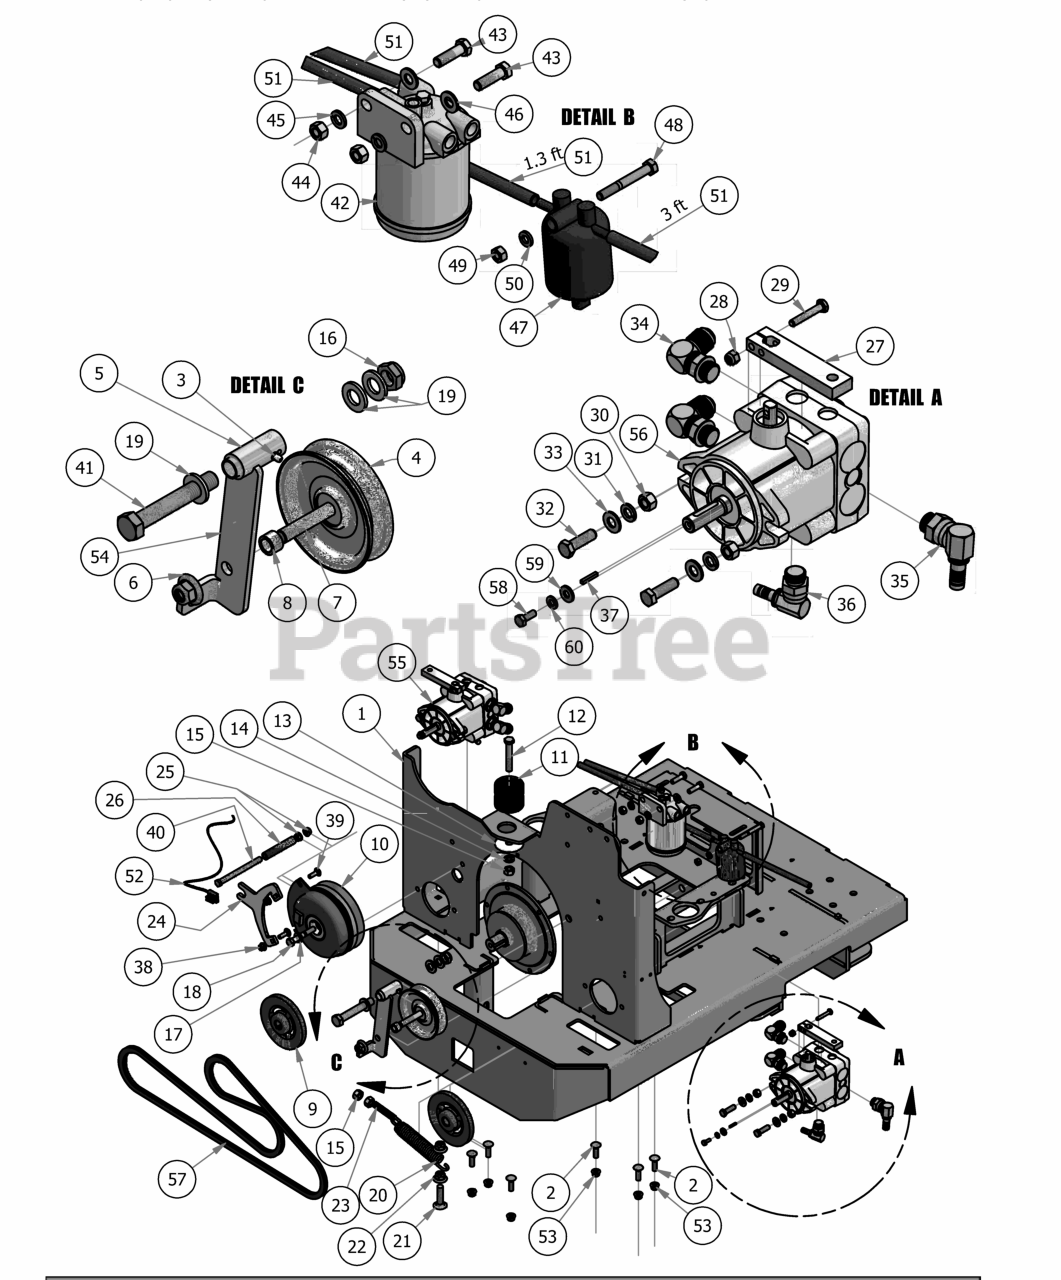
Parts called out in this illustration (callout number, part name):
1	Pump Plate Diesel
2	3/8" x 1 1/4" Carriage Bolt
3	1/4" Drive in Grease Fitting
4	4 3/4" Idler Pulley
5	Pump Idler Bracket only for 61" Deck
6	1/2-13 Nylon Flange Nut-Orange
7	1/2" x 3" Hex Bolt
8	1/2 x 1/2 Spacer
9	5" Pump Pulley
10	Clutch Assembly for Diesel
11	Armor Plated Mount-Rear Mount
12	1/2" x 3" Hex Bolt
13	Snubbing Washer
14	1/2" Lock Washer
15	1/2" Hex Nut
16	5/8" Nylock (1/2 Jam)
17	7/16" Lock Washer
18	7/16" x 2 3/4" Fine Thread Bolt
19	.630 ID x 1.122 OD x .142 THK Plastic Washer
20	Deck Idler Spring
21	1/2 x 2" Carriage Bolt
22	1/2-13 Nylon Flange Nut-Orange
23	1/2-13 x 2-1/2 All Thd Stud
24	Diesel PTO Engager Holder
25	3/8" Flange Nut
26	3/8 hose 4" long
28	1/4" Nylock Nut
29	1/4" x 1 1/2" Bolt
30	3/8" Hex Nut
31	3/8" Lock Washer
32	3/8" x 1 1/2" Hex Bolt
33	3/8" Flat Washer
34	6801-LL-8-8 Fitting - Compact Diesel
35	90 Degree Fitting 1/2" x 3/4" 4601-8-8
36	90 Degree Fitting 3/8" X 9/16"- 4601-6-6
37	5mm x 1.25" Key
38	5/16" Flange Nut
39	5/16" x 1" Carriage Bolt
40	3/8-16 x 5 Hex Bolt - Grade 5
41	5/8" x 4" Hex Bolt 61" Deck only
42	Fuel Filter
43	3/8" x 1 1/4" Hex Bolt
44	3/8" Hex Nut
45	3/8" Lock Washer
46	3/8" Flat Washer
47	Caterpillar Fuel Bowl Kit
48	5/16" x 2 1/2" Bolt
50	5/16" Lock Washer
51	5/16" fuel line hose
52	Clutch Pigtail
53	3/8" Nylock Flange Nut
54	Pump Idler Assembly Components 3,4,5,6,7,8, only for 61" Deck
55	Left Pump 16cc - With Fan
56	Right Pump 16cc - With Fan
57	Pump Belt for 61" Deck
58	M6-1.0 X 16MM Hex Bolt
59	1/4" Flat Washer
60	1/4" Lock Washer
